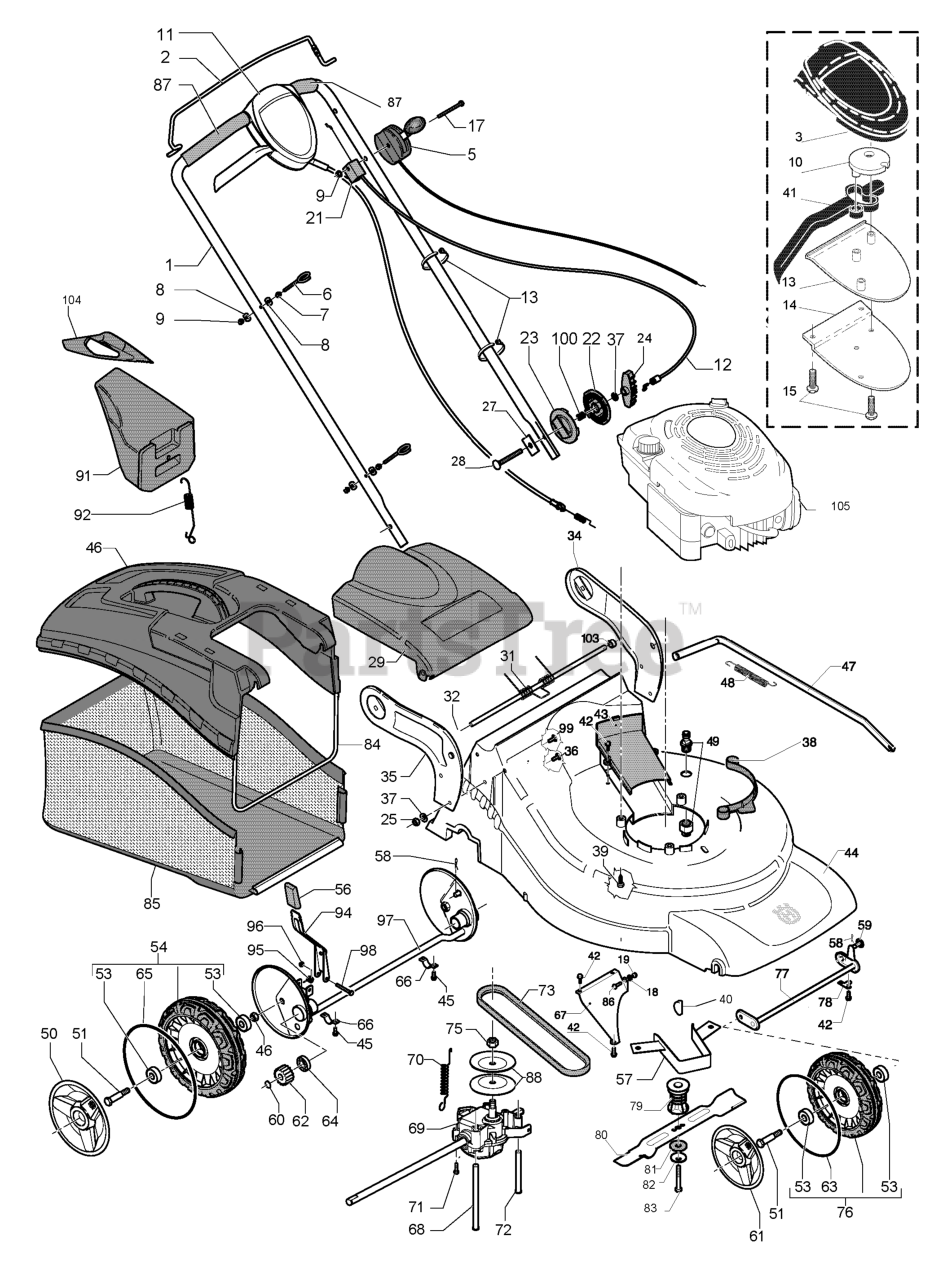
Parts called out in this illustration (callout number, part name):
3	CASE.TOP.GRAY
10	PULLEY.CAM.DRIVE.CONTROL.HV
12	BRAKE WIRE
14	BRACKET, DRIVE CONTROL
15	SCREW, PHILLIPS HEAD 10 X 5/8
29	DEFLECTOR 51 CAST ORANGE
31	SPRING 51 CAST
41	LEVER
46	COVER HARD TOP
84	FRAME 51 CAST
97	REAR AXLE REAR AXLE WELDED FOR
